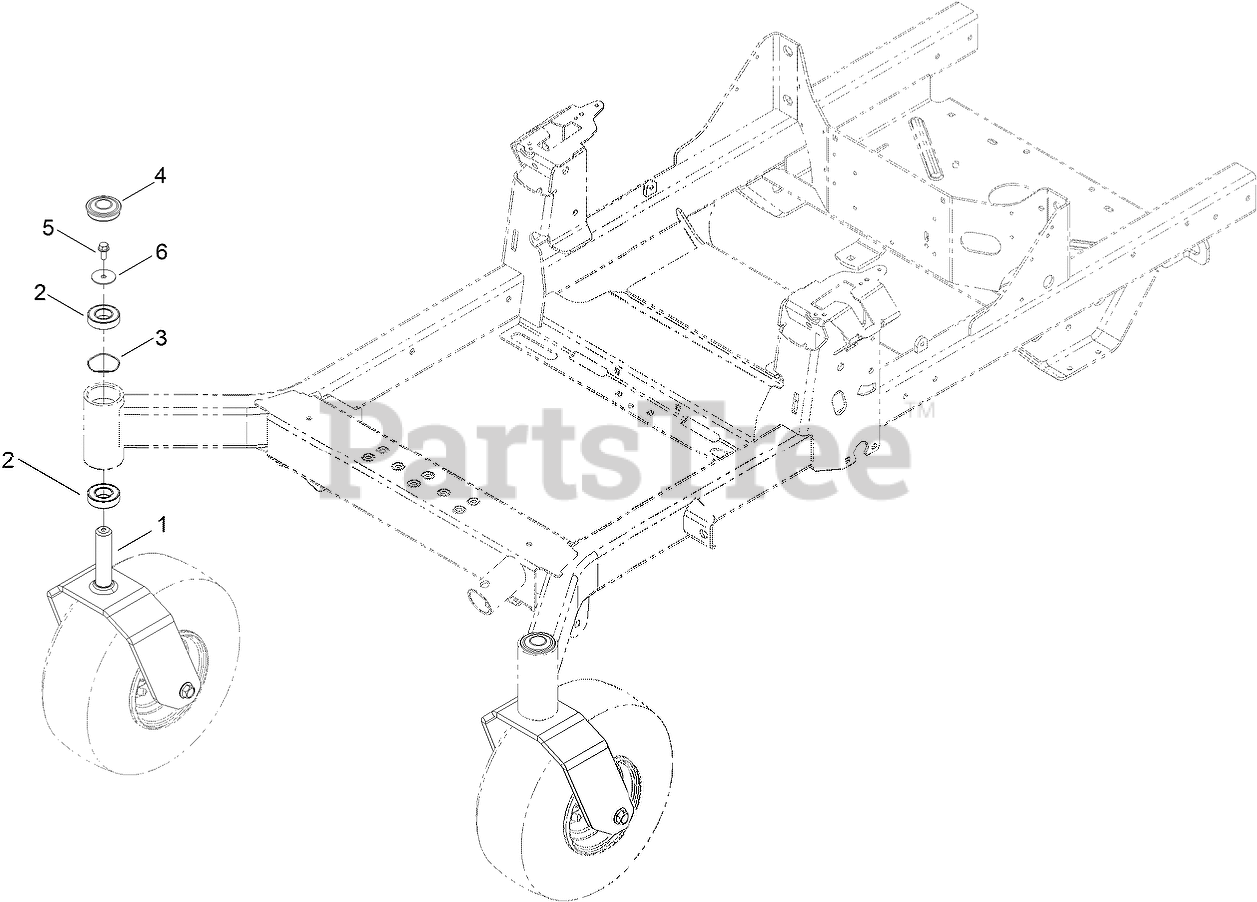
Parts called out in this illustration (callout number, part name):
1	ASM-FRONT CASTER W/FORK
2	BEARING-BALL
3	SPRING
4	CAP,GREASE
5	SCREW-HHF
6	WASHER-FLAT
